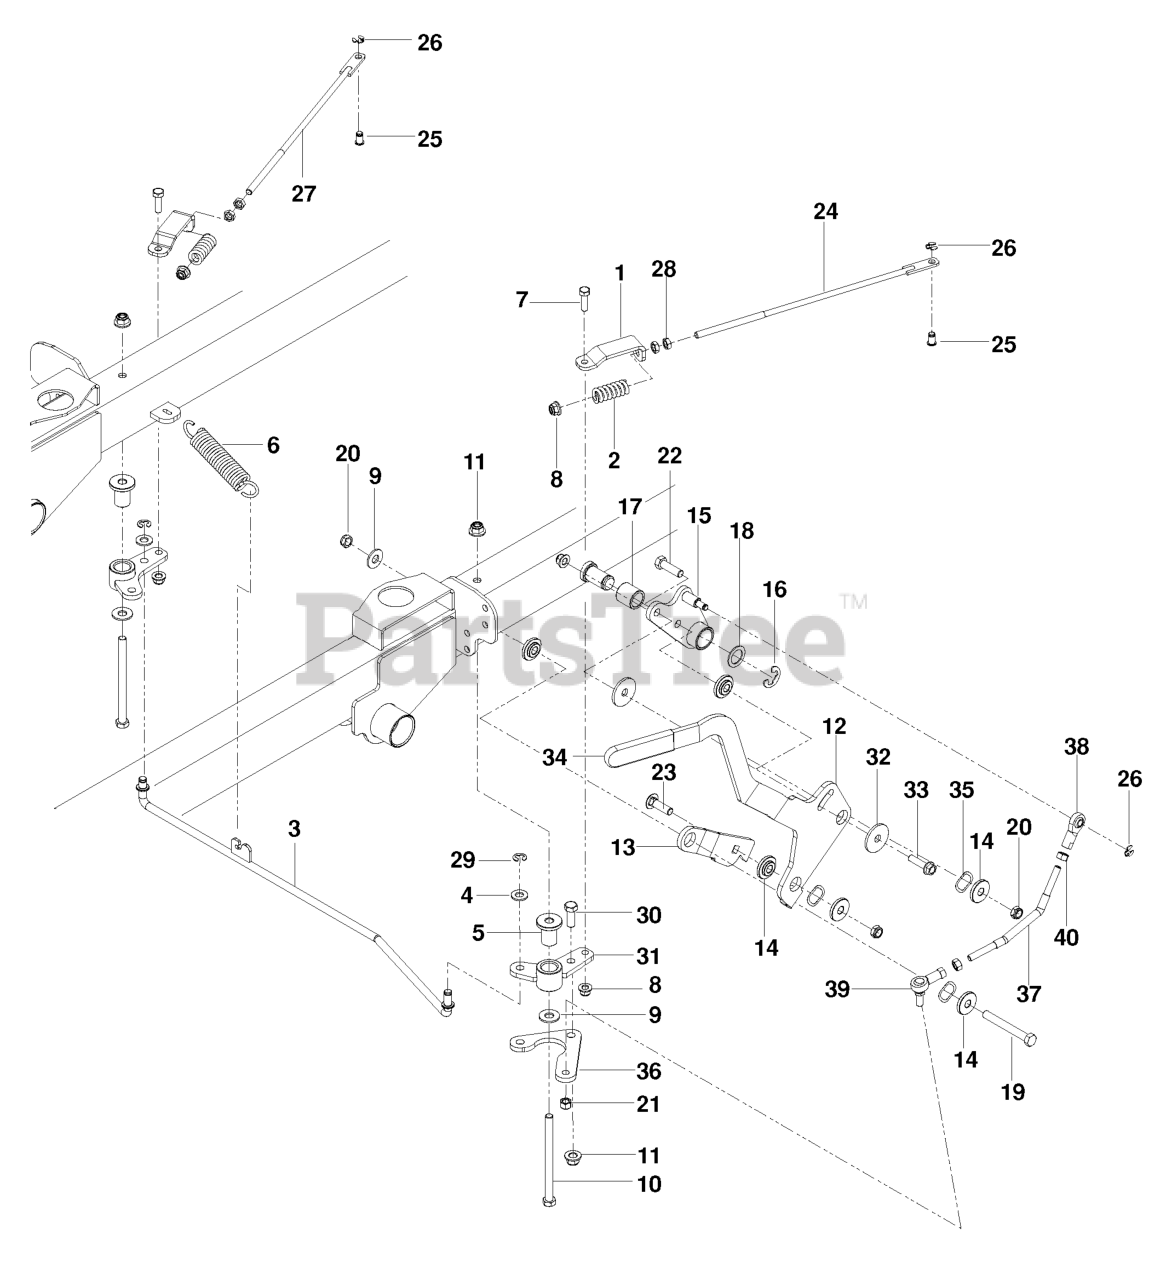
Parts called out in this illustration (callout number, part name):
1	BRACKET, BRAKE
3	LINKAGE, BRAKE, PRIMARY
4	WASHER 3/8 SAE FLAT
5	BUSHING, PIVOT
7	HCS 5/16C X 1
8	5/16-18 NYLOC FLANGE NUT
9	WASHER 3/8 FLAT
10	SCREW, 3/8C X 5 HEX CAP
11	NUT 3/8-16 HEX FLG NYLOC ZD
12	LEVER.BRAKE.BLACK
13	LINK, FOLLOWER
14	BUSHING, BRAKE
15	WELDMENT, ARM, BRAKE
16	E RING 3/4
17	BUSHING, SLEEVE 3/4 X 1.0
18	WASHER .787 X 1.125 X .06
19	HCS 3/8C X 3
20	NUT HEX 3/8-16 NYLON, THIN
21	NUT 5/16F NYLOC
22	HCS 3/8C X 1 1/4 GR5
23	RHSNB 3/8-16 X 1-1/4
24	LINKAGE, BRAKE RR
25	PIN, BRAKE ARM
26	RING RETAINING EXT 5/16
27	LINKAGE, BRAKE, RT-RR
28	NUT 5/16-18 HEX JAM ZD
29	E RING 3/8"
30	HCS 3/8-16X1.GRD.5.ZD
31	BELLCRANK, BRAKE, WLDMT
32	WASHER, FRICTION, 1/8
33	HHFS 5/16-18 X 1.25 TPBLT GD 5
35	WASHER, .825 X 1.087, WAVE
36	PLATE, BRAKE, BLK
37	LINKAGE, BRAKE
38	BALL JOINT, RIGHT HANDED
39	SPHERICAL ROD END, RH
